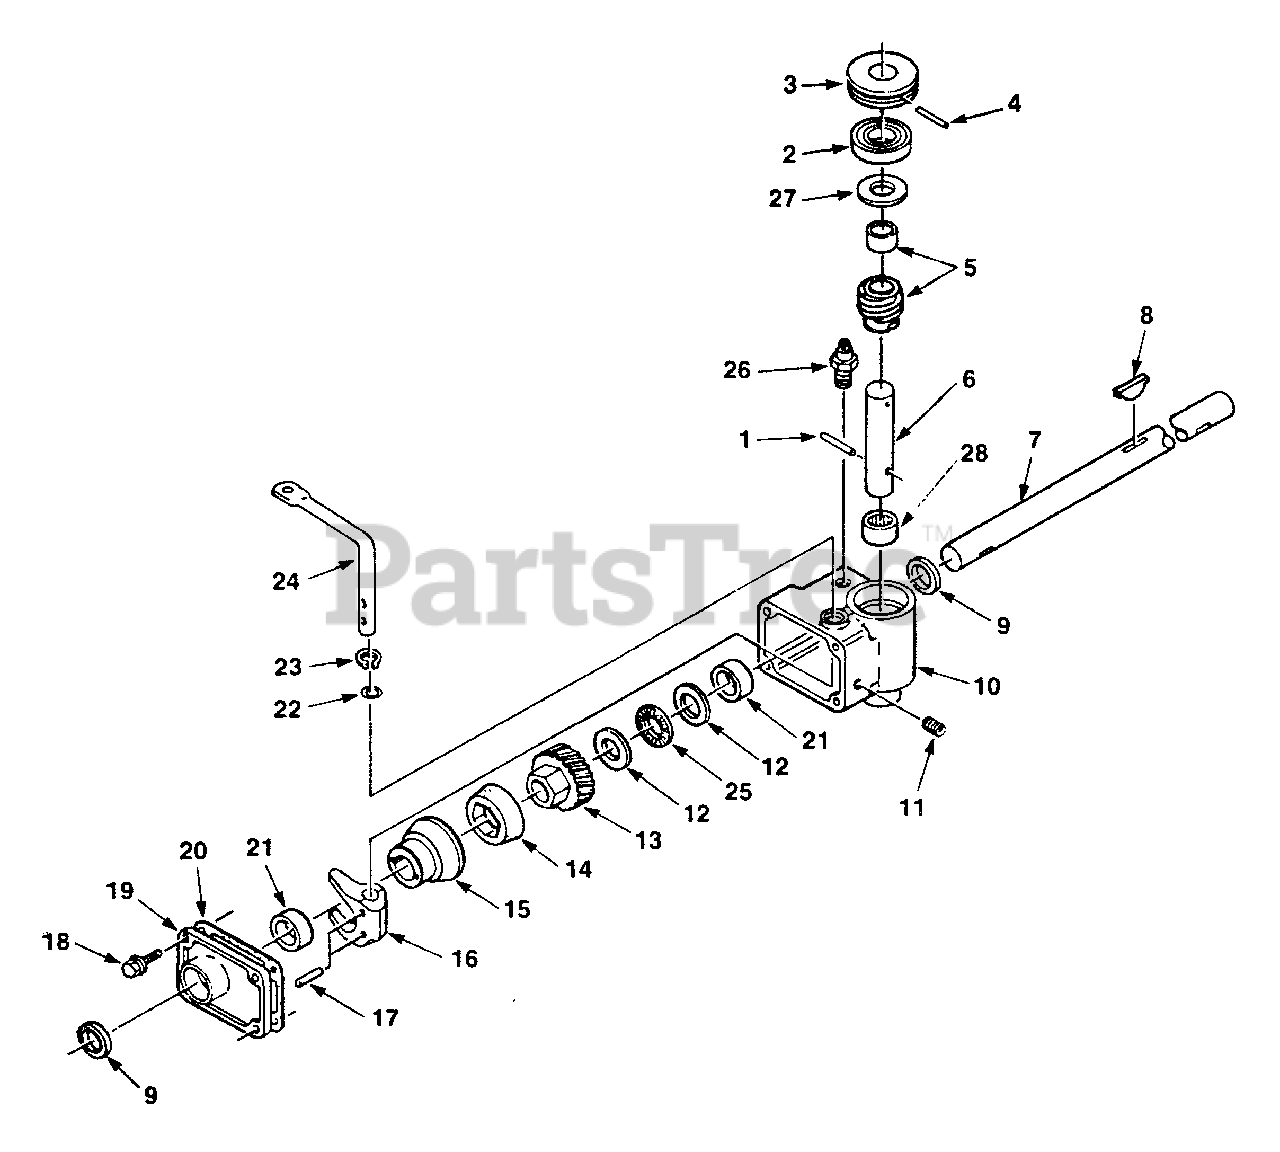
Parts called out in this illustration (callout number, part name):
1	PIN
2	BEARING, BALL
3	PULLEY
4	PIN 3/32×3/4
5	WORM & SPACER
6	SHAFT, WORM
7	DRIVESHAFT
8	KEY - 1/8×1/2"
9	SEAL
10	GEAR REDUCER HOUSING ASSY
11	PLUG - PIPE
12	RACE - BEARING
13	GEAR, WORM
14	CONE - FRICTION
15	DRUM, CLUTCH
16	FORK - SHIFT
17	PIN 5/32×3/4
18	SCREW - 1/4-20×7/8"
19	LID, GEAR CASE
20	GASKET
21	BUSHING - SLEEVE
22	O-RING
23	RING
24	LEVER - SHIFT
25	BEARING - THRUST
26	VENT
27	WASHER
28	BEARING, NEEDLE
